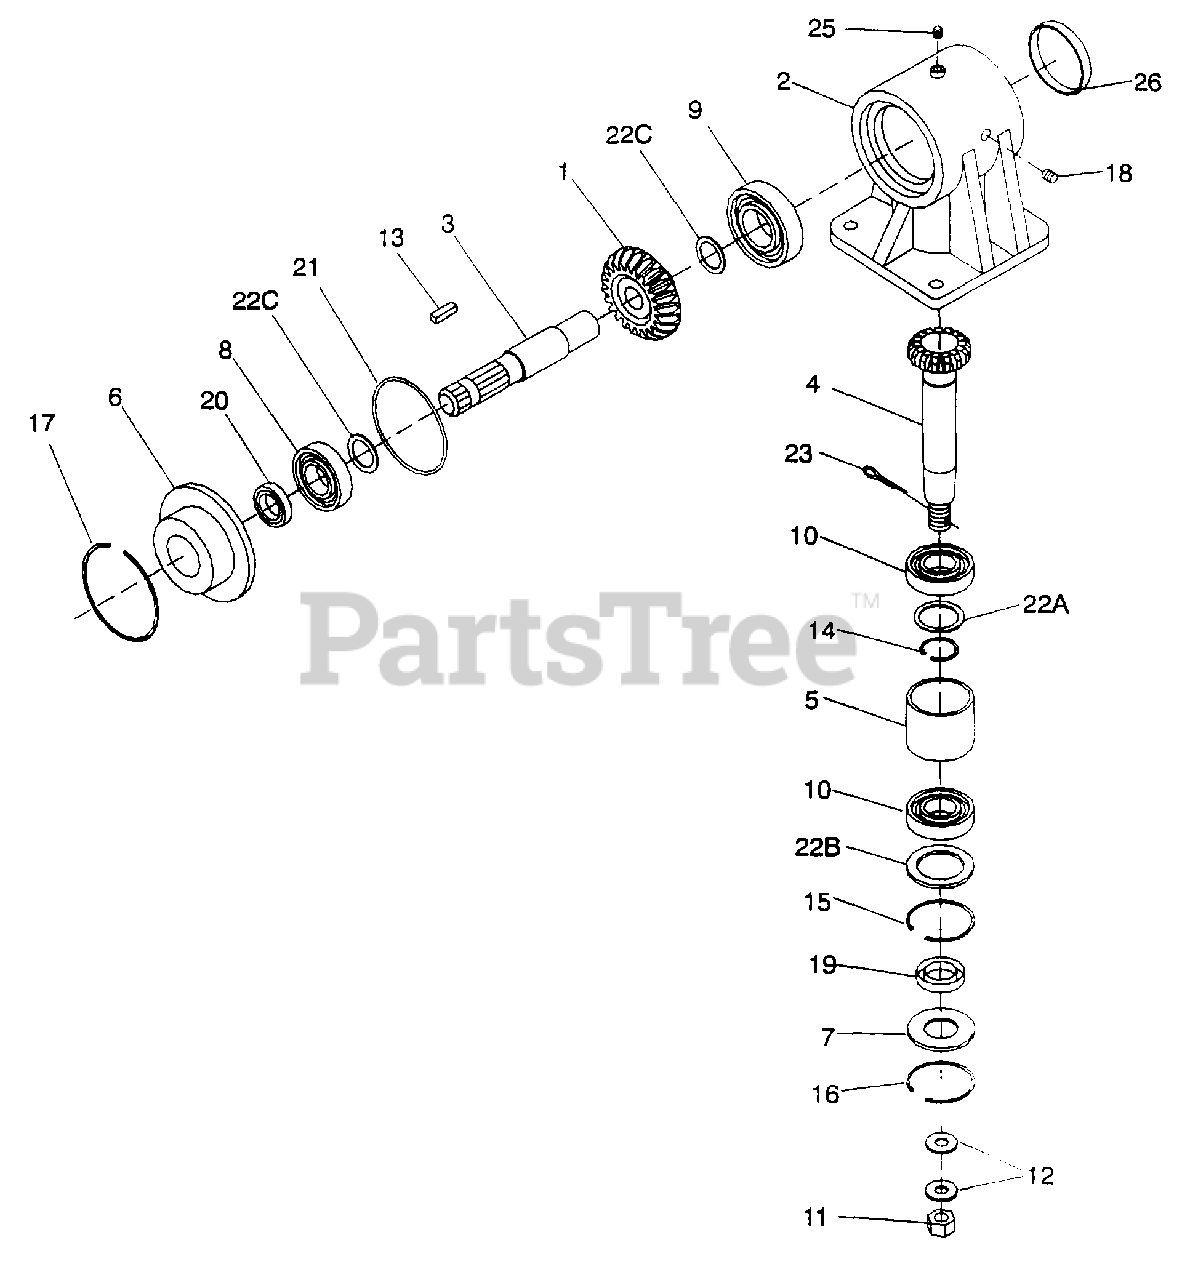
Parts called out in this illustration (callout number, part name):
1	1:1.92 Gearbox with decal
1	1.38 x 4.5 x 237 Gear
2	Gearbox housing
3	.887 Input shaft
4	3.0 x 12T Pinion shaft
5	2.76 x 3.00 x 3.3 Spacer
6	Gearbox cover with decal
7	1.58 x 3.13 x .04 Washer
8	Ball bearing 6007
9	Ball bearing 6207
10	Ball bearing 6208
11	M24 x 2 Castle nut
12	25mm x 44mm x 4mm Washer
13	8mm x 10mm x 30mm Key
14	45mm Retaining ring
15	2.9mm x 80mm Internal retaining ring
16	81mm Internal retaining ring
17	125mm Internal retaining ring
18	3/8 NPT Square head pipe plug
19	40 x 80 x 12 Metric seal
20	35 x 52 x 7 Metric seal
21	.13 x 4.88 OD O-Ring seal
22A	40.3mm x 51.5mm Shim
22B	69.0mm x 79.9mm Shim
22C	35.3mm x 48.0mm Shim
23	3/16 x 2 Cotter pin
25	3/8 NPT Vent plug
26	Cap, 52mm dia. x 7mm
